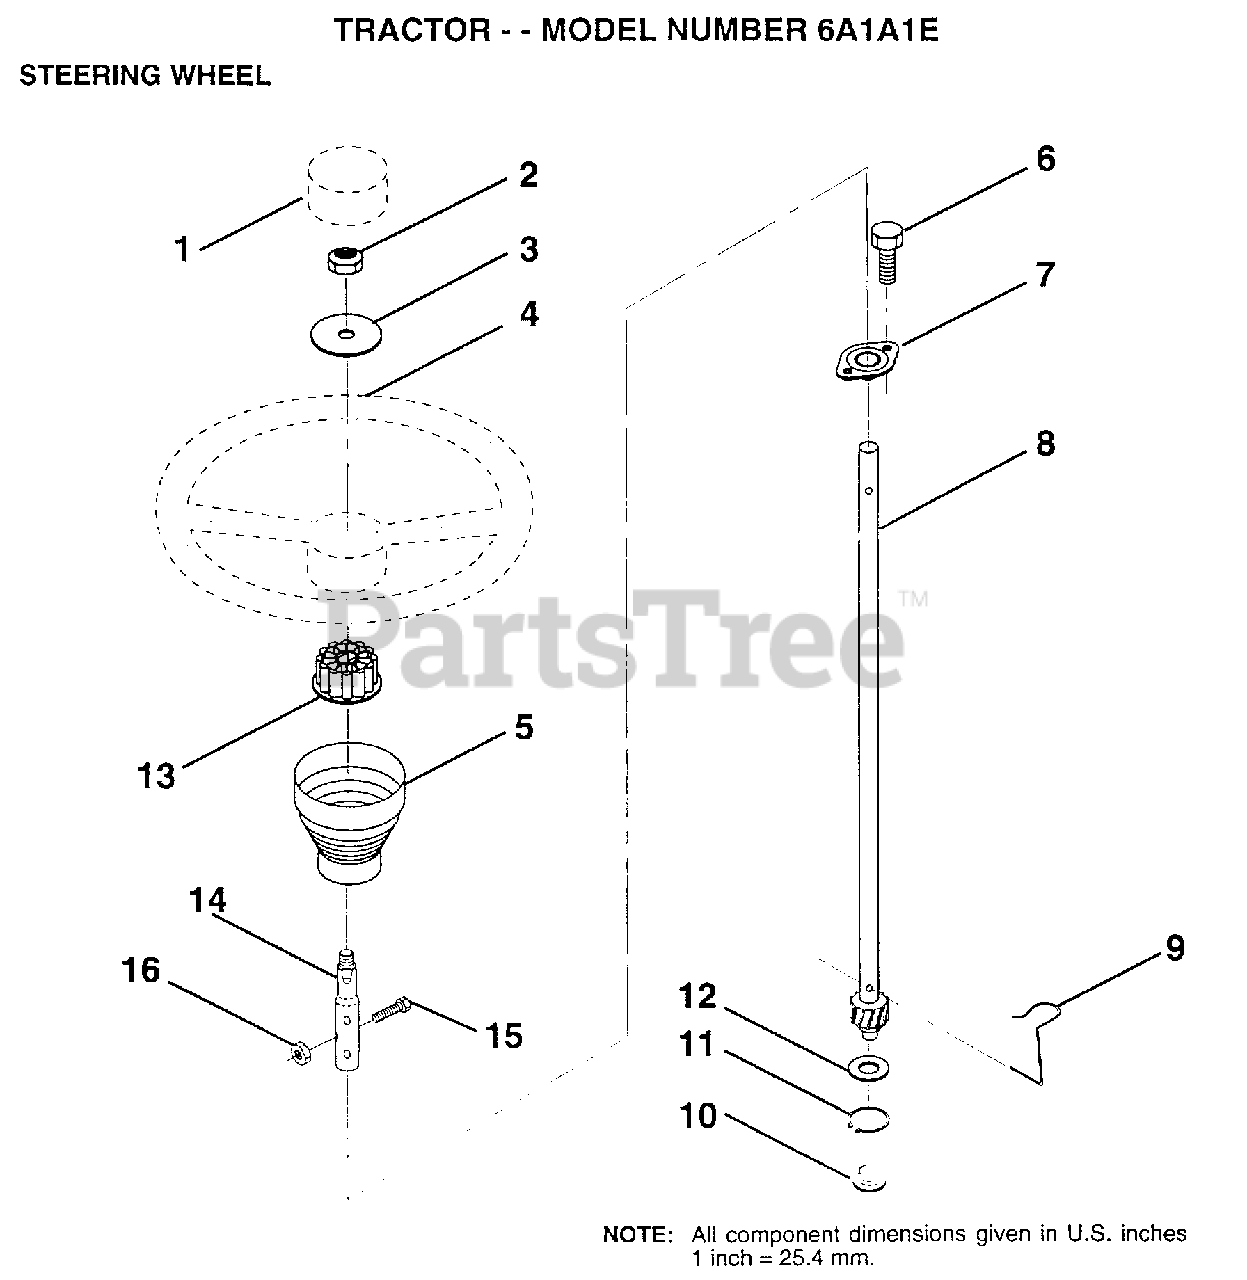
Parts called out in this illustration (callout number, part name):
1	ST WHL INSERT CAP
2	LOCKWASHER
3	WASHER T
5	SLEEVE STEERING
8	SHAFT.STEERING.LR
9	STEERING CLIP
10	BUSHING STEER LWR
11	RING
12	WASHER LT
13	ADAPTER LT
14	EXT SHAFT STEERIN
15	BOLT
16	NUT
17	BOLT
